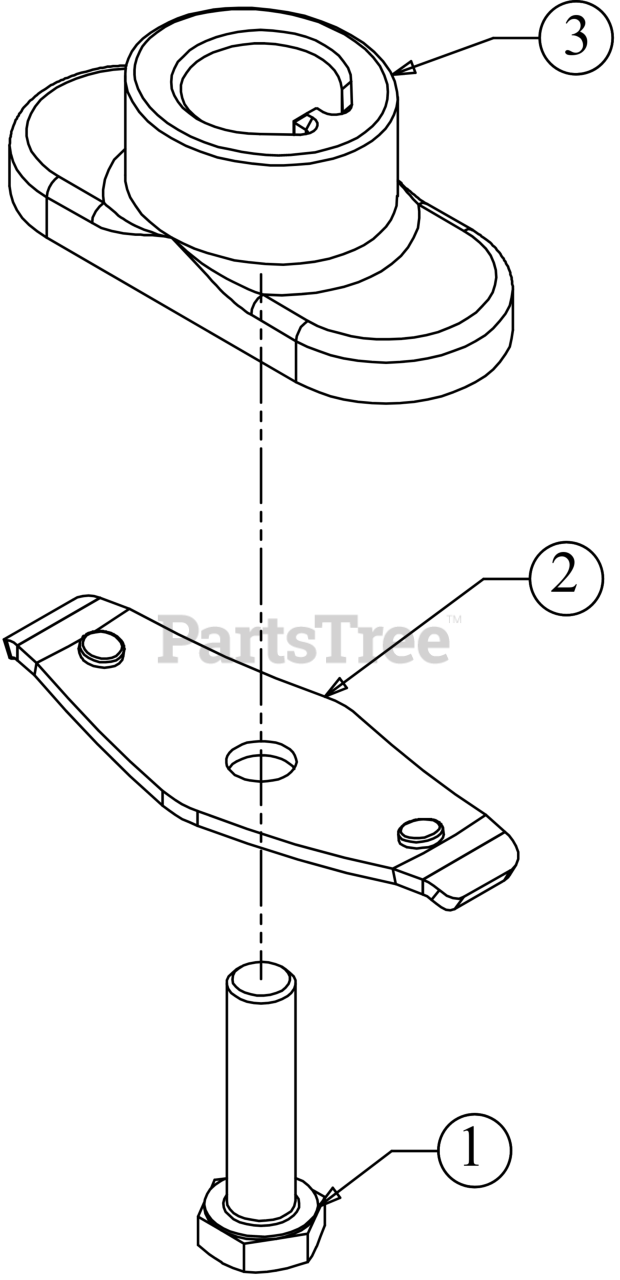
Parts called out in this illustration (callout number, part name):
1	SCREW 3/8-24 X 1.50 GR8
2	BLADE BELL SUPPORT
3	BLADE ADAPTER-W/STAR
3	BLADE ADAPTER KIT
